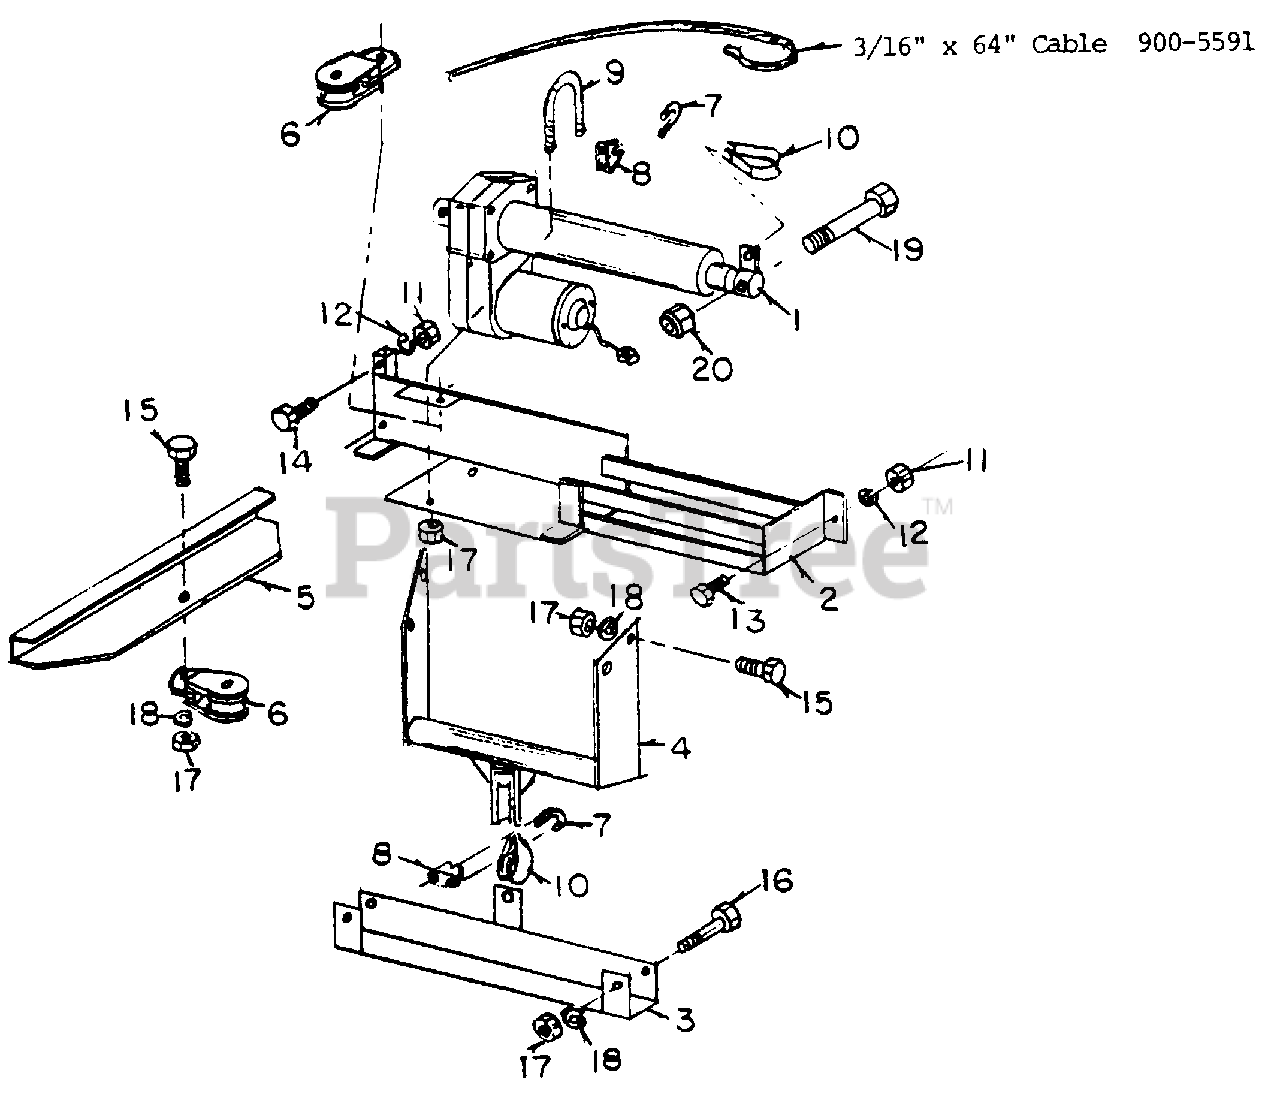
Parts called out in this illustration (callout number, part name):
1	Actuator
2	Actuator Mount
3	Dock Lift Adaptor
4	Cable Mount
5	Cable Mount
7	U-Bolt
9	U-Bolt
11	3/4-20 Nuts
12	3/4 Lock Washers
13	1/4-20 x 3/4
14	1/4-20 x 1
15	5/16-18 x 1
16	5/16-18 x 2
17	5/16-18 Nut
18	5/16 Lock Washers
19	1/2-13 x 4
20	1/2-13 Lock Nut
